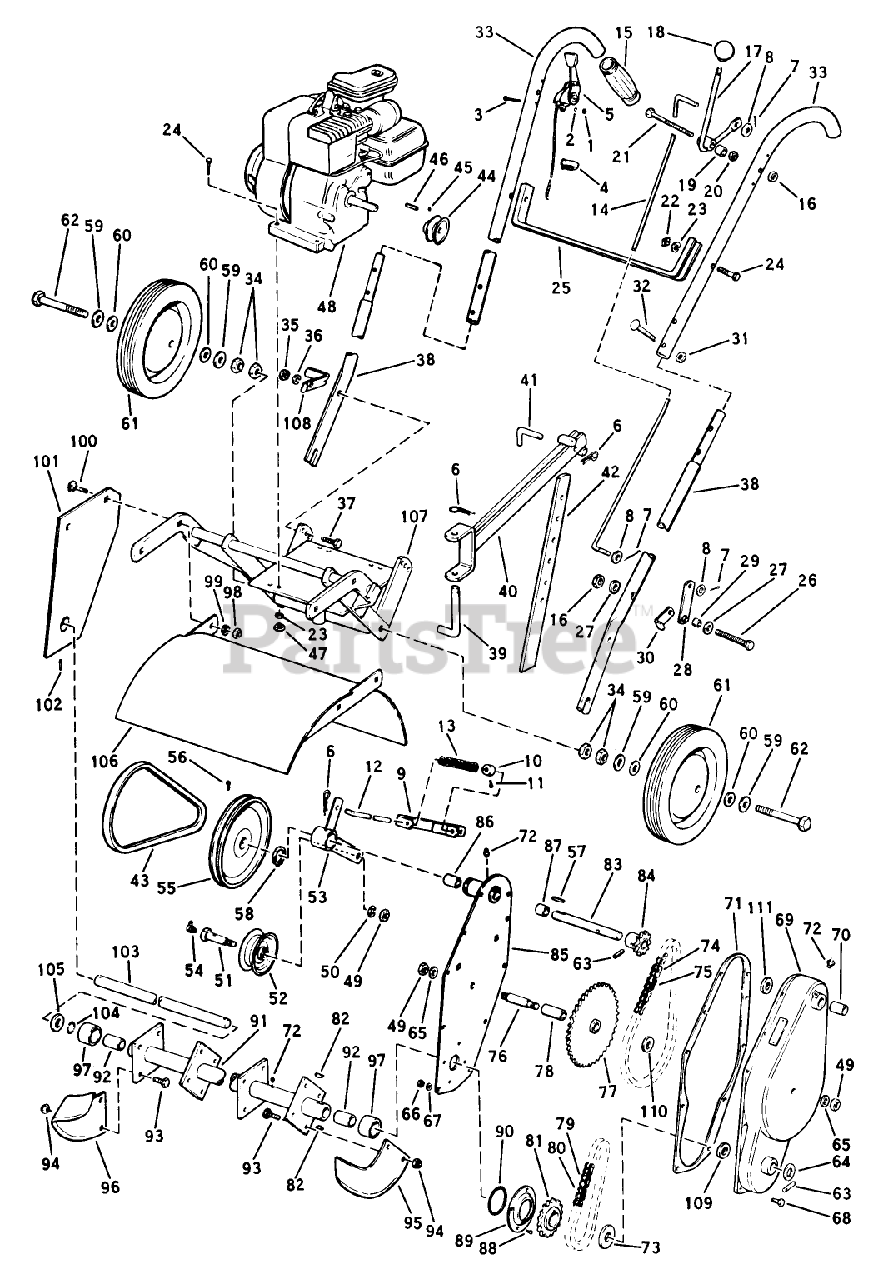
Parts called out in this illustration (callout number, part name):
2	Lockwasher
3	Machine Screw #8-32 x 1-1/2 Lg.
4	Cable Clip
5	Throttle Control Assembly
9	Spring Bracket Assembly
11	Set Screw
12	Engine 8 H.P.
13	SRV BULLT 437B
17	Control Lever Assembly
23	WASHER, LOCK
28	Shifting Lever
32	Square Nut 5/16-18
34	Hex Jam Nut 1/2-13
35	LOCKNUT
37	Capscrew 3/8-16 x 1-1/4 Lg.
38	Handle Bar Tube Assembly
40	Beam Assembly
41	Selector Pin
42	Depth Bar
48	Engine (B S)
52	Idler Pulley
53	Idler Arm Assembly
56	Set Screw
60	Rubber Washer
61	Wheel Assembly 10 x 1.75
62	Hex Head Axle Bolt 1/2-13 x 4 Lg.
63	Roll Pin
65	Lockwasher, Shakeproof
67	WASHER-LOCK
69	Cover Assembly
72	Grease Fitting
73	Thrust Washer
74	Chain #41-1/2 Pitch, 55 Links
76	Intermediate Shaft
77	Sprocket Cluster Assy
78	Bushing
79	Extension-Chute
82	Woodruff Key
84	Input Sprocket and Hub Assv.
85	Back Plate Assembly
88	Self Tapping Screw #8-32 x 1/4 Lg.
89	Oil Seal Retainer
91	Rotor Tube Assembly
96	Tine LH
98	Nut-Hex
99	WASHER, LOCK
100	Carriage Bolt 3/8-16 x 1 Lg.
101	Side Plate Assembly
102	Roll Pin
103	Rotor Shaft
106	Hood Assembly
